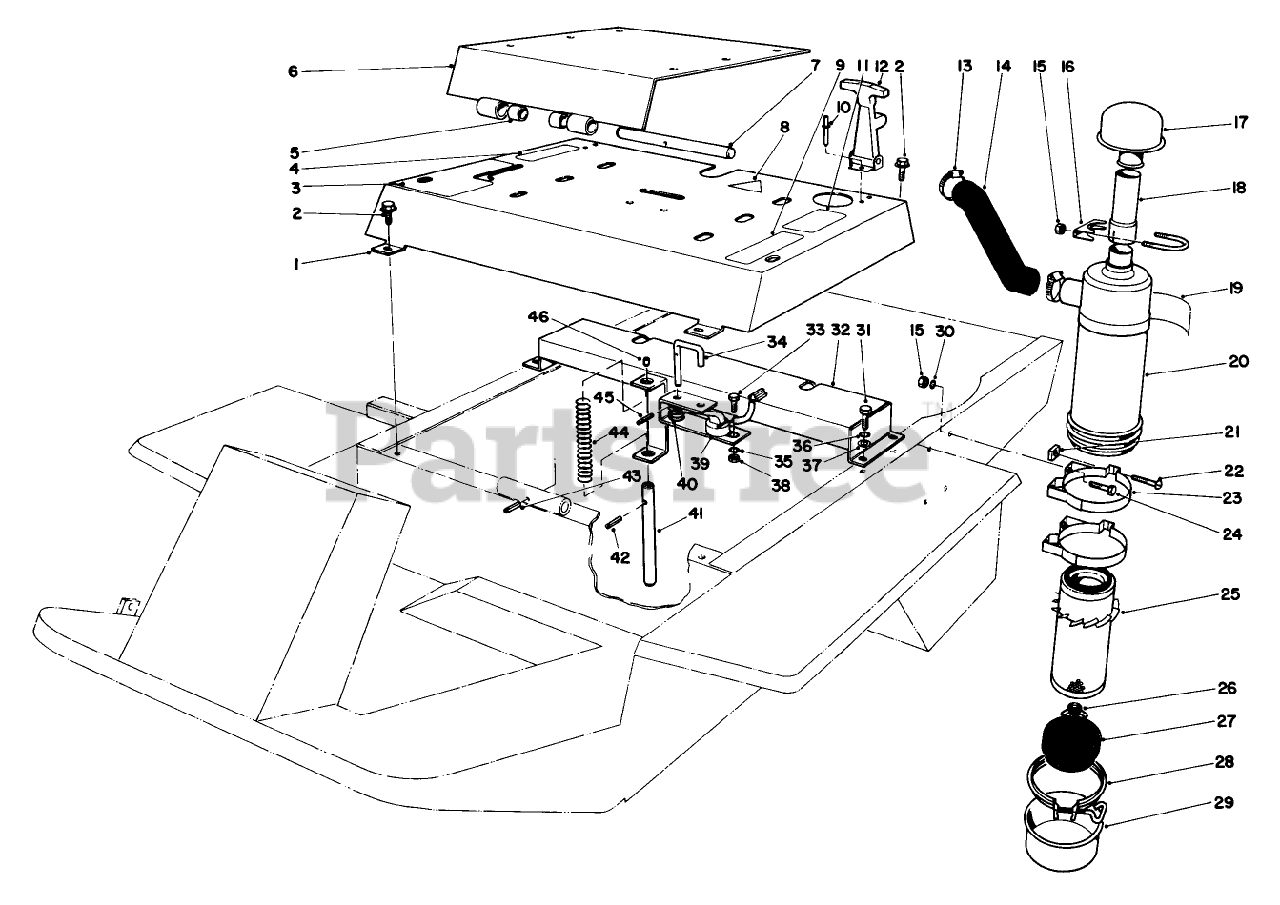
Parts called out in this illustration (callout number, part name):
2	SCREW-HHFTF
5	.503ID X .875LG BSHG
6	SEAT MTG WA
7	SHAFT-PIVOT, SEAT
8	DECAL-DANGER
10	NUT-LOCK, NI
11	DECAL-REFUELING
13	CLAMP-HOSE
15	NUT-HEX
16	CLAMP-MUFFLER
19	DECAL-INSTALLATION
20	AIR CLEANER ASM
21	NUT-SQUARE
22	SCREW
23	MOUNTING BAND ASM
24	SCREW-HH
26	NUT AND GASKET ASM
27	SKIRT-BAFFLE
28	CLAMP ASM
29	A/C CUP ASM
30	SCREW-HH
31	SCREW-HH
33	SCREW-HH
35	SCREW-HH
36	WASHER-LOCK
37	WASHER-FLAT
38	NUT-HEX
40	SPRING
41	PIN-SWITCH, SEAT
42	SCREW-HH
43	SCREW-HH
45	PIN-SPRING
46	PIN-PEDAL
